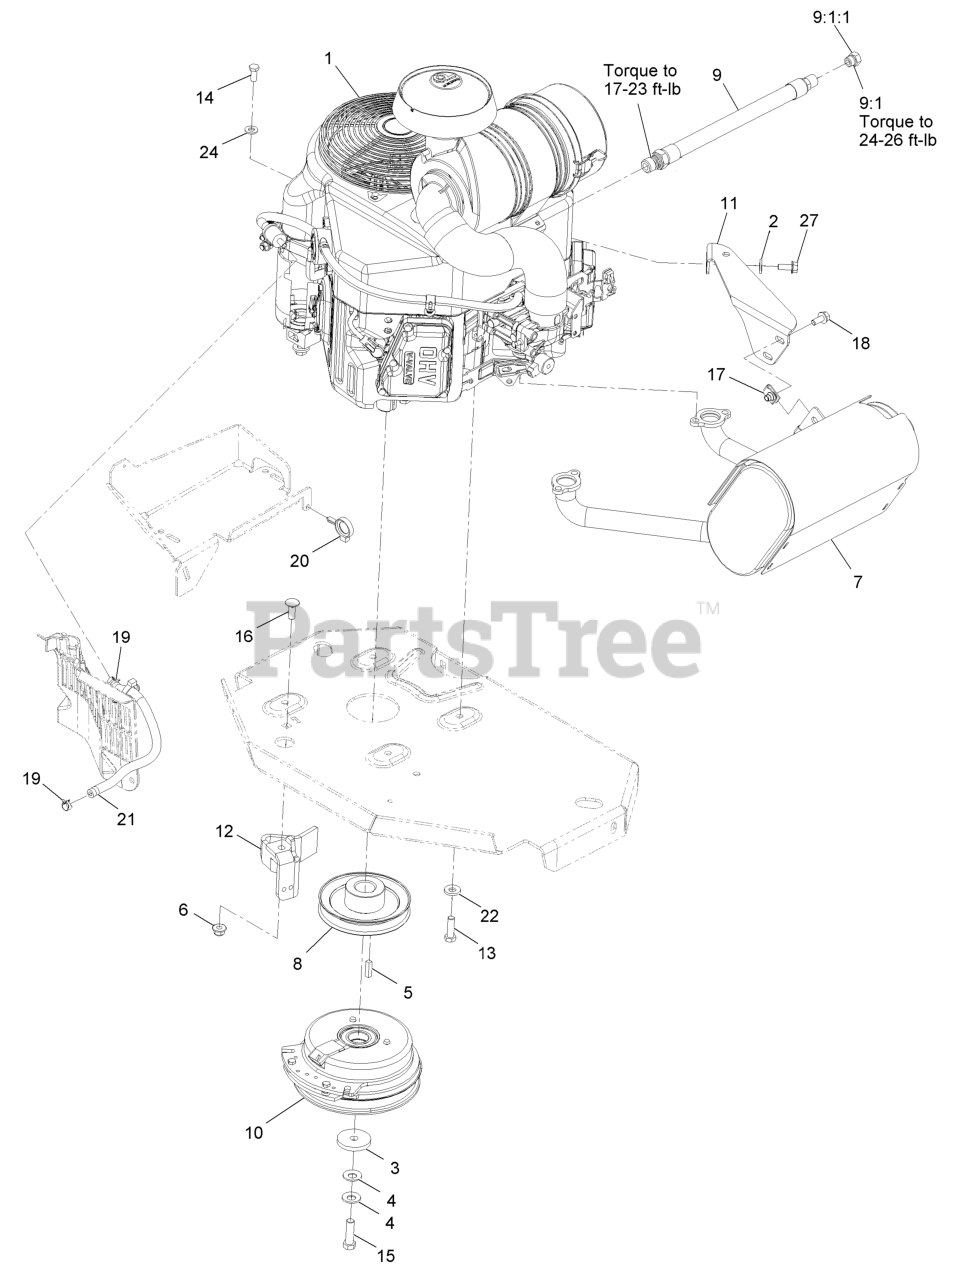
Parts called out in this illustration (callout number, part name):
2	WASHER-SPRING
3	WASHER-CLUTCH
4	WASHER-SPRING
6	NUT-HF, NI
7	MUFFLER
8	SHEAVE-PUMP, DRIVE
9	ENGINE OIL DRAIN HOSE ASM
9:1	PLUG-HH
9:1:1	O-RING
10	CLUTCH KIT
11	BRACKET-MUFFLER
12	CLUTCH-ANCHOR
13	SCREW-HH
14	SCREW-HH
15	SCREW-HH 7/16-20 X 1 1/2 W/LOCTITE
16	SCREW-CARR
18	SCREW-HHF
19	CLAMP-HOSE
20	CLAMP-HOSE
21	HOSE-FUEL
22	WASHER-BELLEVILLE
24	WASHER-PLAIN
27	SCREW-HHF
